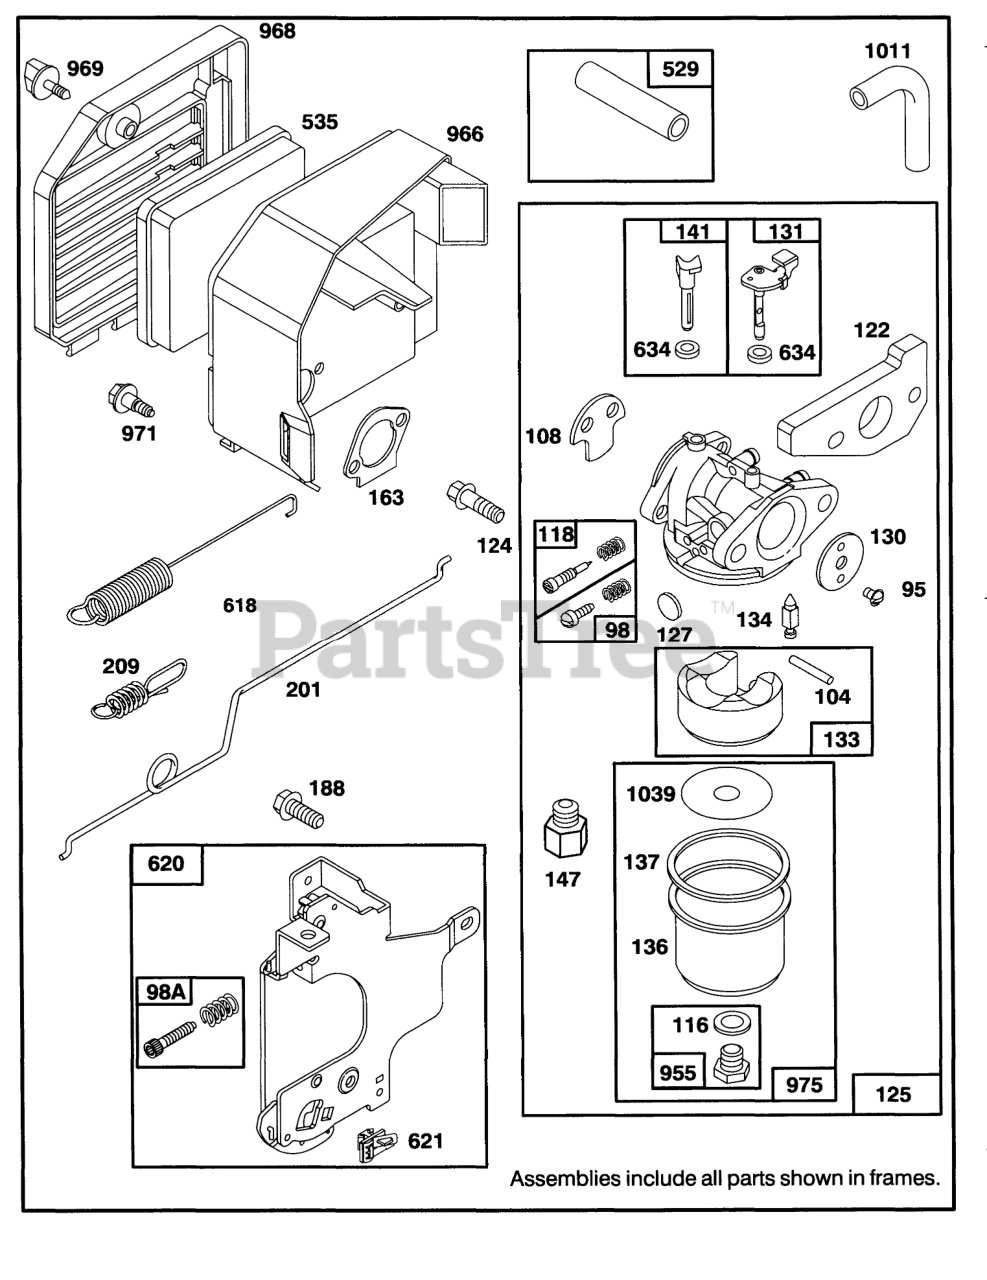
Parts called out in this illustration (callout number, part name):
95	SCREW - ROUND HEAD
98	IDLE ADJUSTING SCREW
98A	SPEED ADJUST. SCREW ASM
104	FLOAT HINGE PIN
108	CHOKE VALVE
116	SEALING GASKET
118	VALVE KIT - NEEDLE
122	ADAPTER ASSEMBLY
124	HEX HEAD SCREW
125	CARBURETOR ASSEMBLY
127	PLUG
130	THROTTLE VALVE
131	THROTTLE SHAFT
133	FLOAT-CARBURETOR
134	Valve-Float (Includes Seat)
136	FLOAT BOWL
137	FLOAT BOWL GASKET
141	CHOKE SHAFT
147	JET ADAPTER
163	AIR CLEANER GASKET
188	SCREW - SEM
201	GOVERNOR LINK
209	GOVERNOR SPRING
529	BREATHER TUBE
535	FILTER ELEMENT
618	RETURN SPRING
620	CARBURETOR BRACKET
621	STOP SWITCH
634	SEAL WASHER
955	HEX HEAD SCREW
966	AIR CLEANER BASE
968	AIR CLEANER COVER
969	AIR CLEANER SCREW
971	AIR CLEANER SCREW
975	CARBURETOR BOWL ASM
1011	VENT TUBE
1039	FLOAT LIMITER
